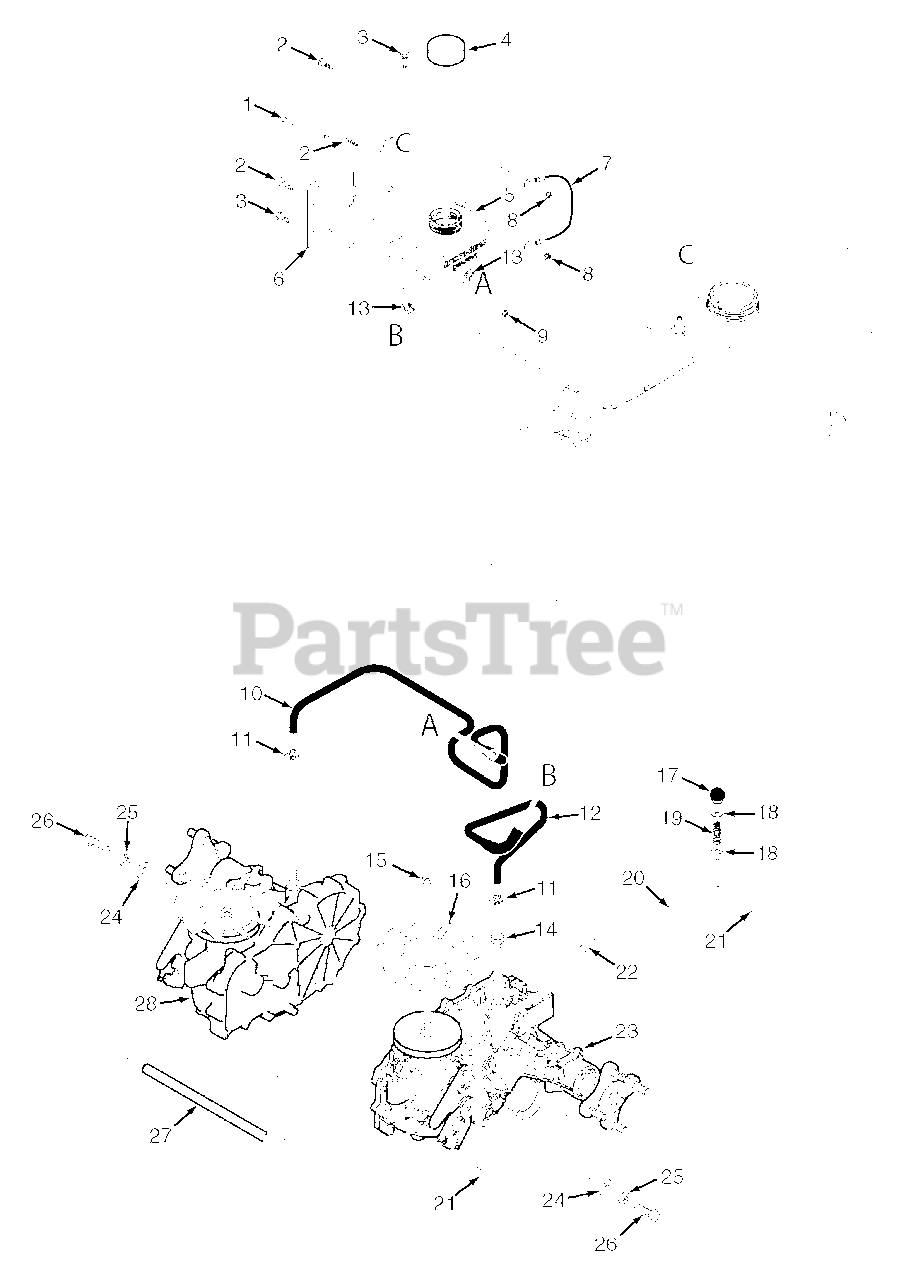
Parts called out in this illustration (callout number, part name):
1	Cover, Oil Reservoir
2	Bolt, Carriage 1/4-20 x 3/4"
3	Bolt, Serrated Flange 1/4-20 x 1/2"
4	Cap, Oil Reservoir
5	Oil Reservoir Assembly
6	Mounting Bracket, Oil Reservoir
7	Lanyard, Oil Reservoir Cover
8	Nut, Flanged Elastic Stop 1/4-20
9	Nut, Elastic Stop 1/4-20
10	Hose, RH Transaxle
11	Clamp, .69 Max Dia.
12	Hose, LH Transaxle
13	Clamp, .87 Max Dia.
14	Fitting, Transmission
15	Fan Nut
16	Fan (order through Hydro-Gear)
17	Knob, Dump Lever
18	Flatwasher, 1/4-.312 x .750 x .065
19	Spring
20	Linkage, Dump Valve
21	Hair Pin Cotter
22	Joint, Swivel
23	Transaxle, LH
24	Flatwasher, 3/8-.391 x .938 x .105
25	Lockwasher, 3/8" Spring
26	Bolt, Hex Head 3/8-16 x 2-1/4"
27	Spacer, Axles
28	Transaxle, RH
